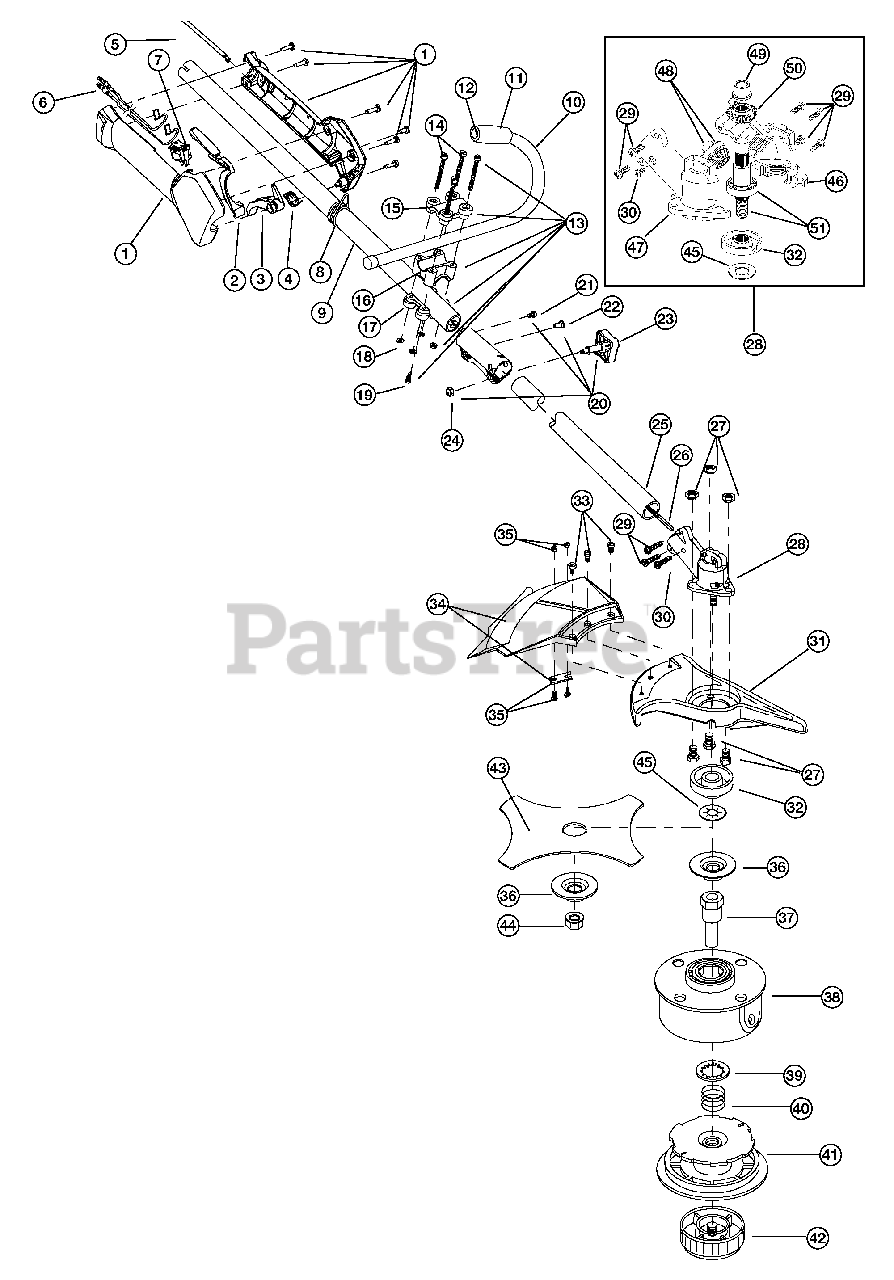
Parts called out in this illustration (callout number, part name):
1	Throttle Housing & Trigger Assembly
2	Throttle Trigger Lock-Out
3	Throttle Trigger
4	Throttle Trigger Spring
5	Throttle Cable Assembly
6	Lead Wire Assembly
7	Switch Assembly
8	Harness Clip
9	Upper Drive Shaft Housing Assembly
10	J-Handle Assembly
12	Tube Closure
13	Handle Bracket Assembly
15	Upper Handle Clamp
16	Middle Handle Clamp
17	Lower Handle Clamp
19	Anti-Rotation Screw
20	Click-Link Coupler
23	Adjustment Knob
24	Knob Retaining Nut
25	Lower Drive Shaft Housing Assembly
26	Lower Flexible Drive Shaft
27	Shield Mount Screw Assembly
28	2 piece Gearbox Assembly
29	Gearbox Mounting Hardware
30	Anti-Rotation Screw
31	Blade Shield/Shield Mount
32	Blade Driver
33	Shield Mounting Screw
34	Shield and Blade Assembly
35	Blade Assembly
36	Retaining Washer
37	Spool Shaft
38	Outer Spool Assembly
39	Retainer
41	Inner Reel
42	Bump Head Knob Assembly
43	4-Tooth Blade
44	Nut
45	Palnut
46	Left Housing
47	Right Housing
48	Pinion Gear Assembly
49	Output Shaft Bushing
50	Output Shaft Gear
51	Output Shaft Assembly
